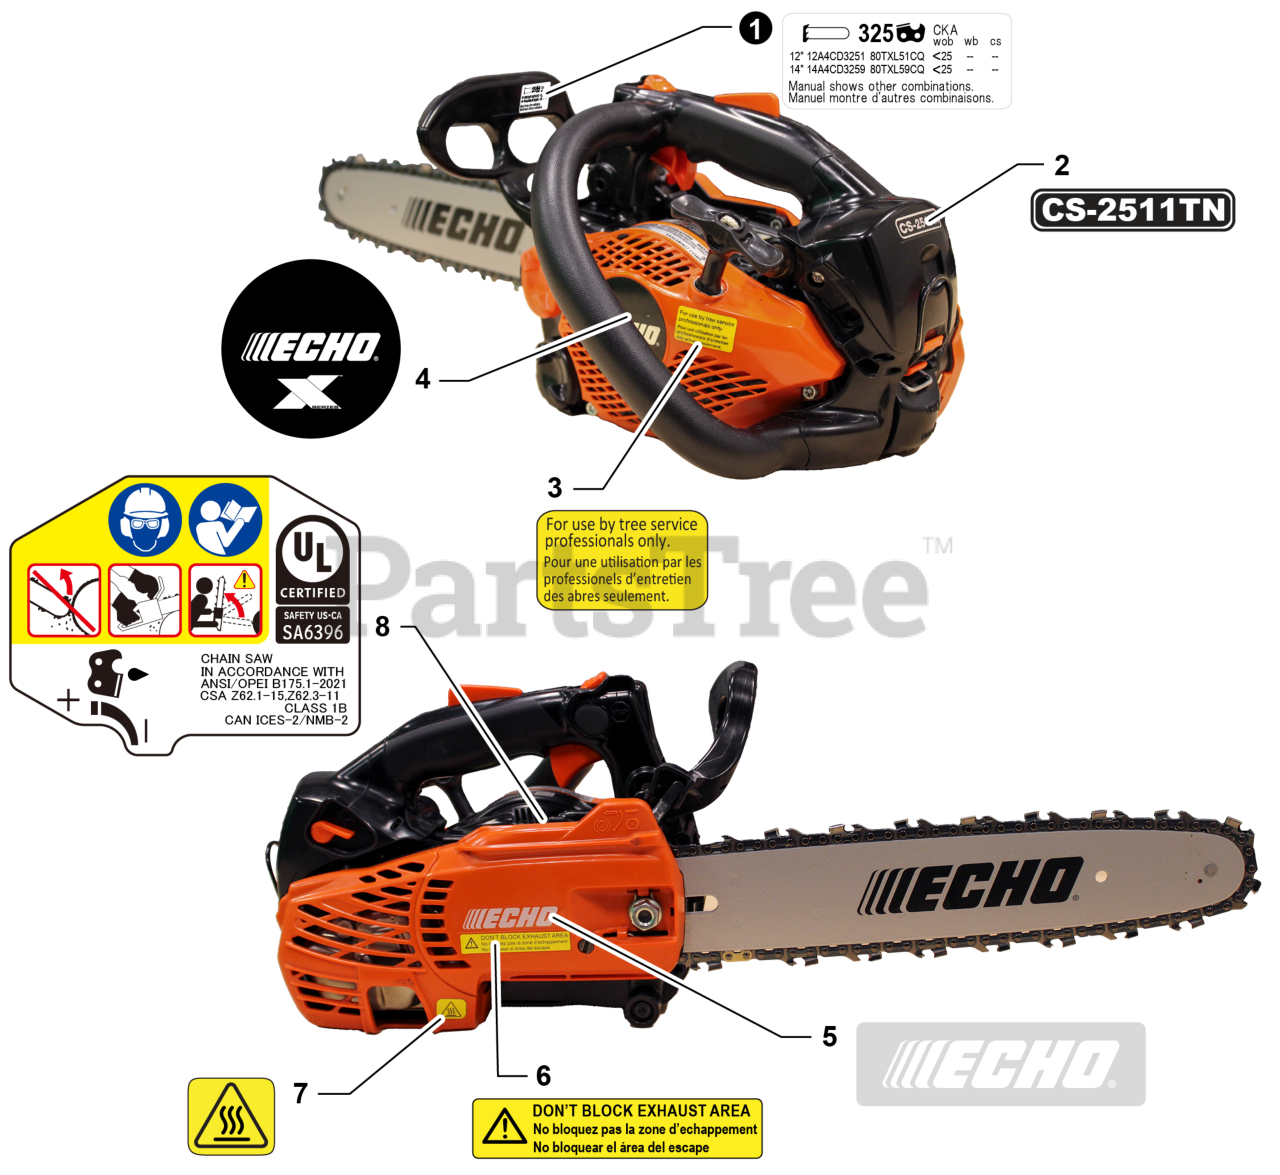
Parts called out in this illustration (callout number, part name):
1	LABEL - BAR & CHAIN
2	LABEL - CS-2511TN
3	LABEL - CAUTION - PROFESSIONALS ONLY
4	LABEL - ECHO
5	LABEL - ECHO
6	LABEL - CAUTION - DON'T BLOCK EXHAUST AREA
7	LABEL - CAUTION - HOT
8	LABEL - CAUTION
